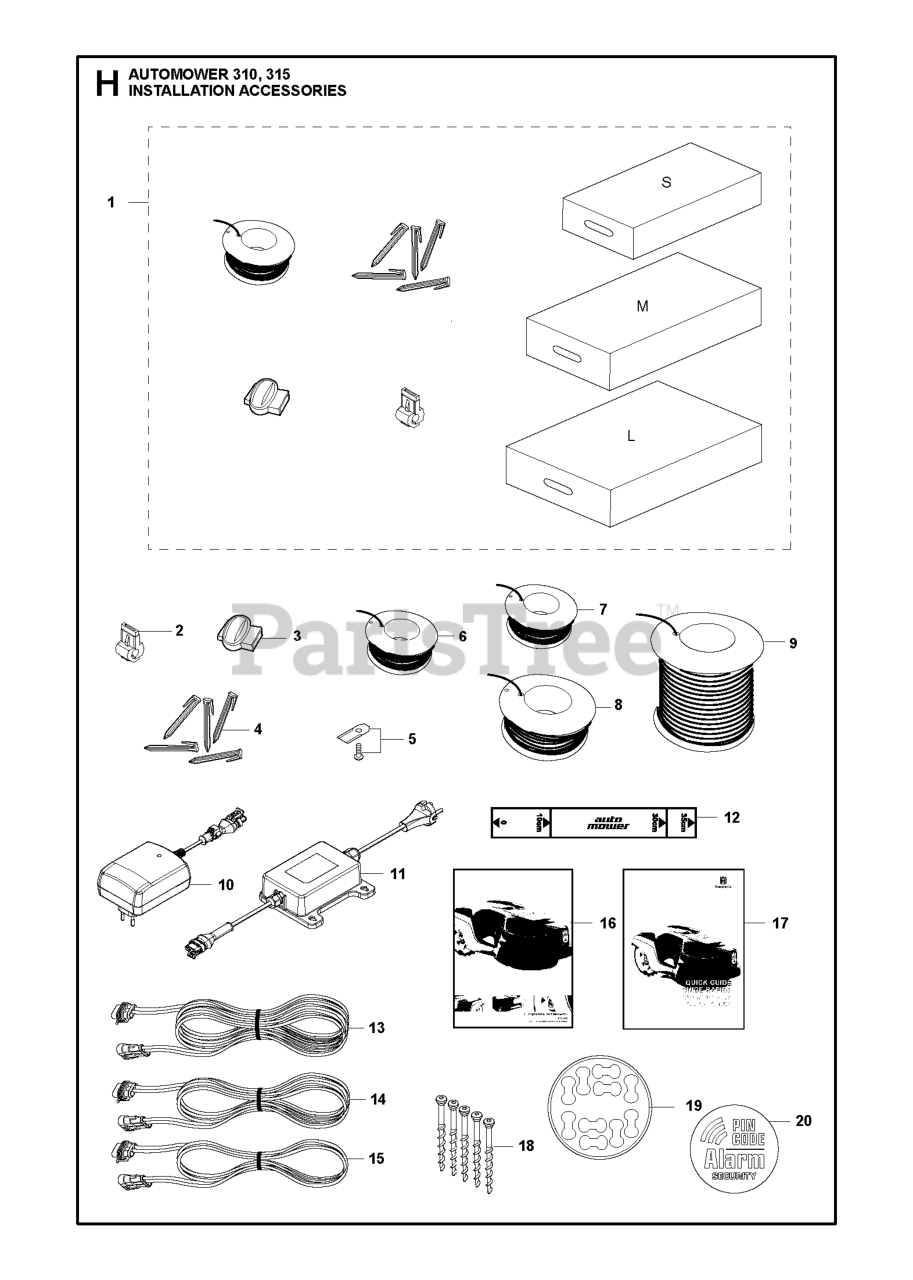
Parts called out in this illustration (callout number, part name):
1	MED AUTOMOWER INSTALL KIT
1	SMALL AUTOMOWER INSTALL KIT
1	LARGE AUTOMOWER INSTALL KIT
2	CONNECTOR 5 PCS, BLISTER
2	BRAKER
3	COUPLER SPLICER, 5 PCS,
3	SPLICE KIT
3	COUPLER SPLICER, 100 PCS
4	STAPLE 100 PCS
5	BLADE SET 45 PCS
5	BLADE KIT HUSQVARNA 9 PCS 50HR
5	BLADE SET 300 PCS. CARBON STEE
6	WIRE BOUNDARY 150M
6	WIRE 150M, BLISTER
7	WIRE 250M
8	WIRE 500M
9	WIRE (800M)
10	POWER UNIT POWER SUPPLY 1,3A
11	POWER UNIT US
12	RULER / CENTIMETERS
13	LOOM LOW VOLTAGE CABLE 20 METE
14	LOOM LOW VOLTAGE CABLE 10 METE
15	LOOM LOW VOLTAGE CABLE 3 METER
15	CABLE ASSY LOW VOLTAGE CABLE
18	SCREW KIT ANCHOR SCREW 5 PCS
19	STICKER CABLE MARKERS KIT 10PC
20	LABEL SECURITY
